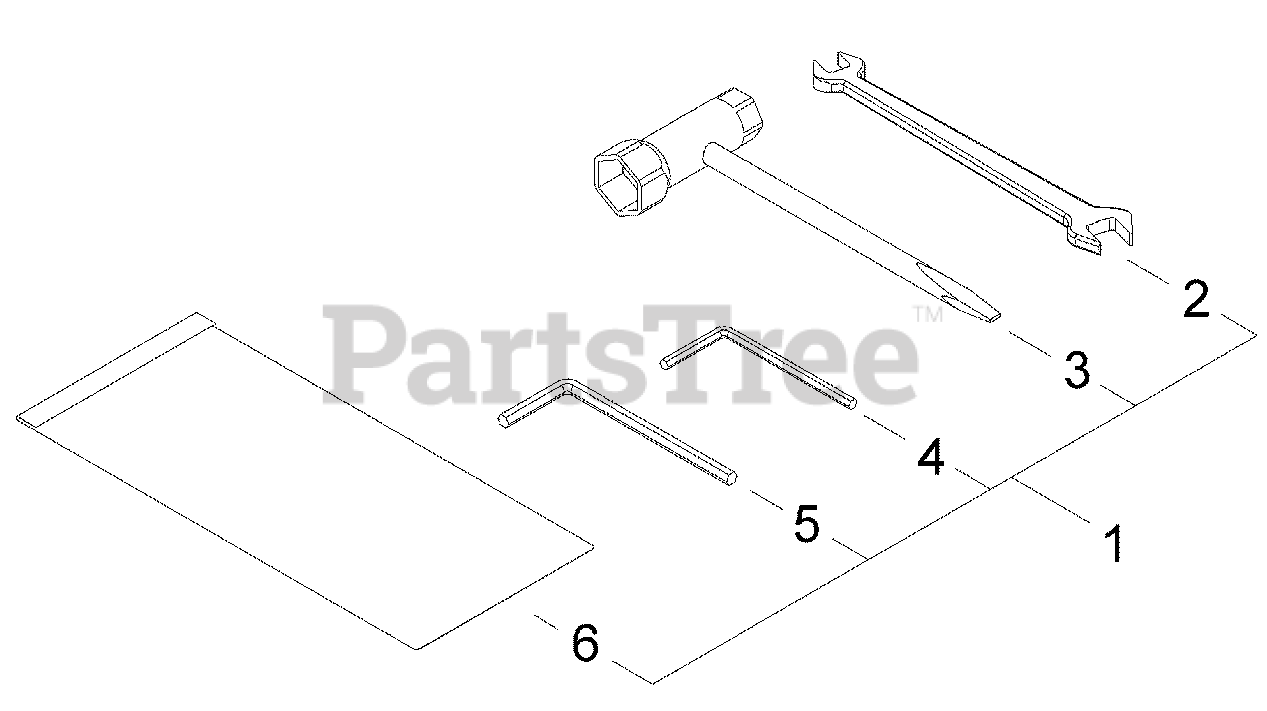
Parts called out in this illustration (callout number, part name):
1	TOOL KIT, SERVICE
2	SPANNER 8×10
3	T-WRENCH 16×13
4	WRENCH, ALLEN 4 MM
5	WRENCH, ALLEN 5 MM
6	BAG, TOOL
